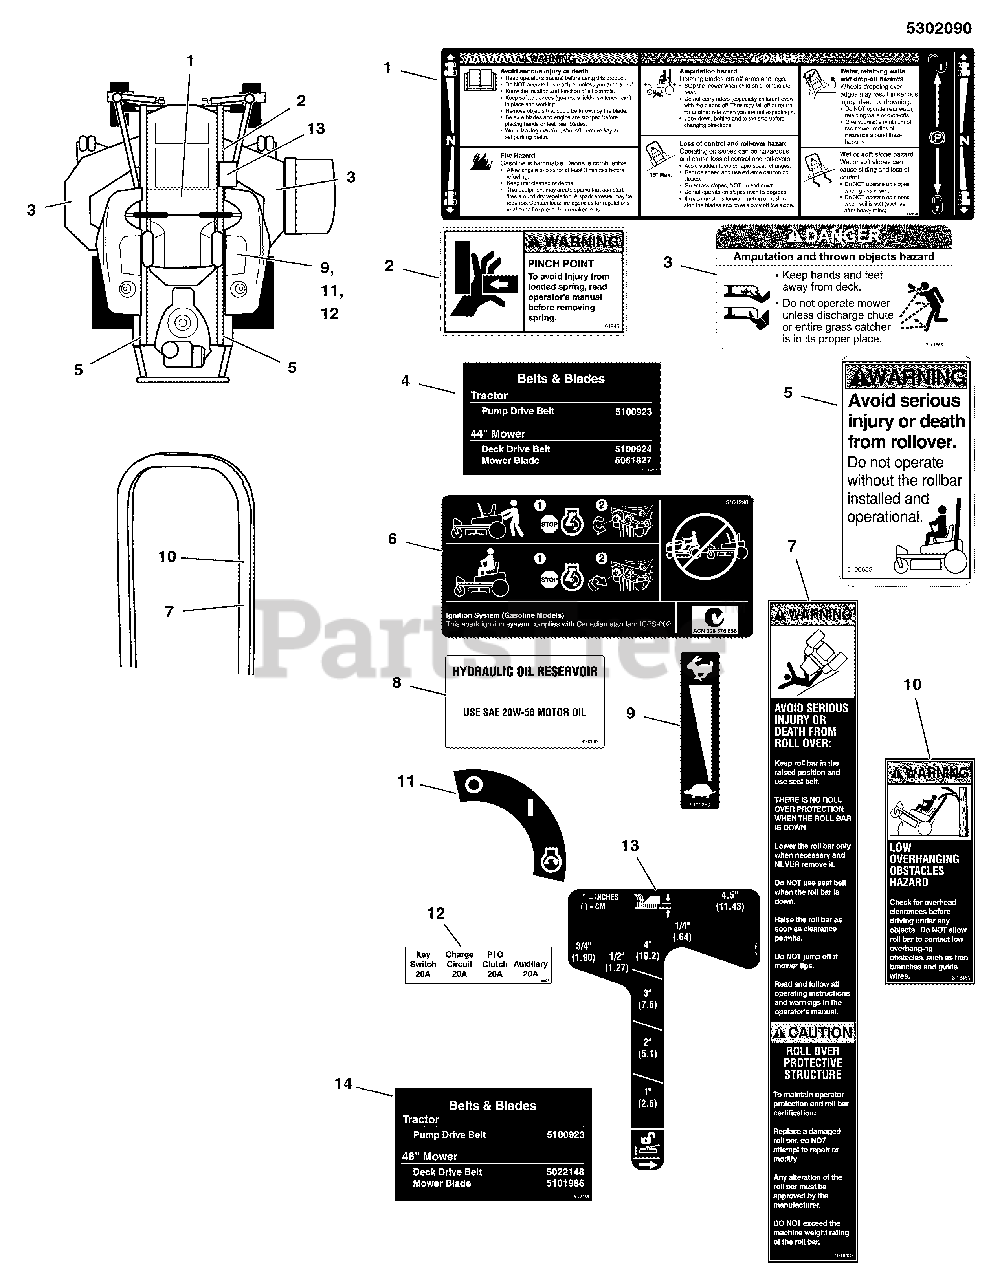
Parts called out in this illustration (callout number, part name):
1	DECAL, MAIN SAFETY
2	DECAL, PINCH POINT
3	DECAL, DANGER DO NOT OPERATE W/O DEFLECT
4	DECAL, BELT & BLADE, SMI ZT4000
5	DECAL, WARNING, ROLL BAR
6	DECAL, CZT HYRDO RELEASE
8	DECAL, HYDRAULIC OIL, SAE 20W50
9	DECAL, THROTTLE CONTROL
10	DECAL, WARNING OVERHANG, ROPS
11	DECAL, IGNITION SWITCH
12	DECAL, FUSE LOCATION
13	DECAL, DECK HEIGHT, IS500Z
14	DECAL, BELT & BLADE, ZT4000-48
